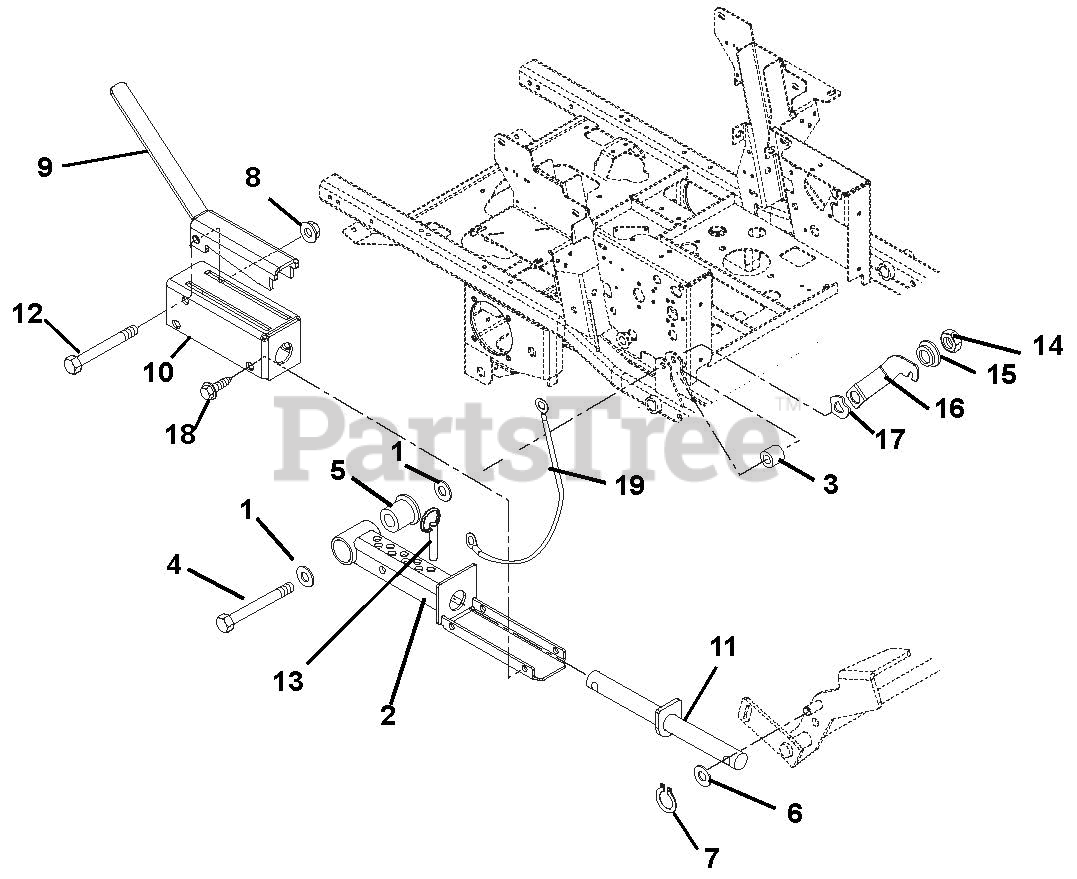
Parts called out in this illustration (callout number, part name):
1	WSHR-FL-STL .531X1.250X.10 YWZ
2	WMT, MECHANICAL LIFT
3	BUSHING, .516X1.000X1.050 LG
4	@BLT-HEX .50-13X5.00 GR5 YWZC
5	BEARING, PEDESTAL
6	@WSHR-FL-STL.656X1.31X.095 YWZ
7	RG-RTNG-EXT .625X.050
8	@NUT-LK-TOP-FLG .38-16 YWZC
9	MECH DECK LIFT LOCK LEVER- BLK
10	WMT, MECH LIFT COVER
11	WMT, MECH. LIFT SHAFT (.62)
12	@BLT-HEX .38-16X3.25 GR5 YWZC
13	PIN, SPRING BALL .375OD X 1.50
14	@NUT-LK-TOP-FLG .50-13 YWZC
15	BSHG-FLG .515X.750X.285X1.120
16	LATCH, FOOTBOARD
17	WASHER-WAVE .760X1.120X.080
18	@SCR-TAP .38-16X.50 HWH TR YWZ
19	CABLE, 12.0 LANYARD, NYLON
